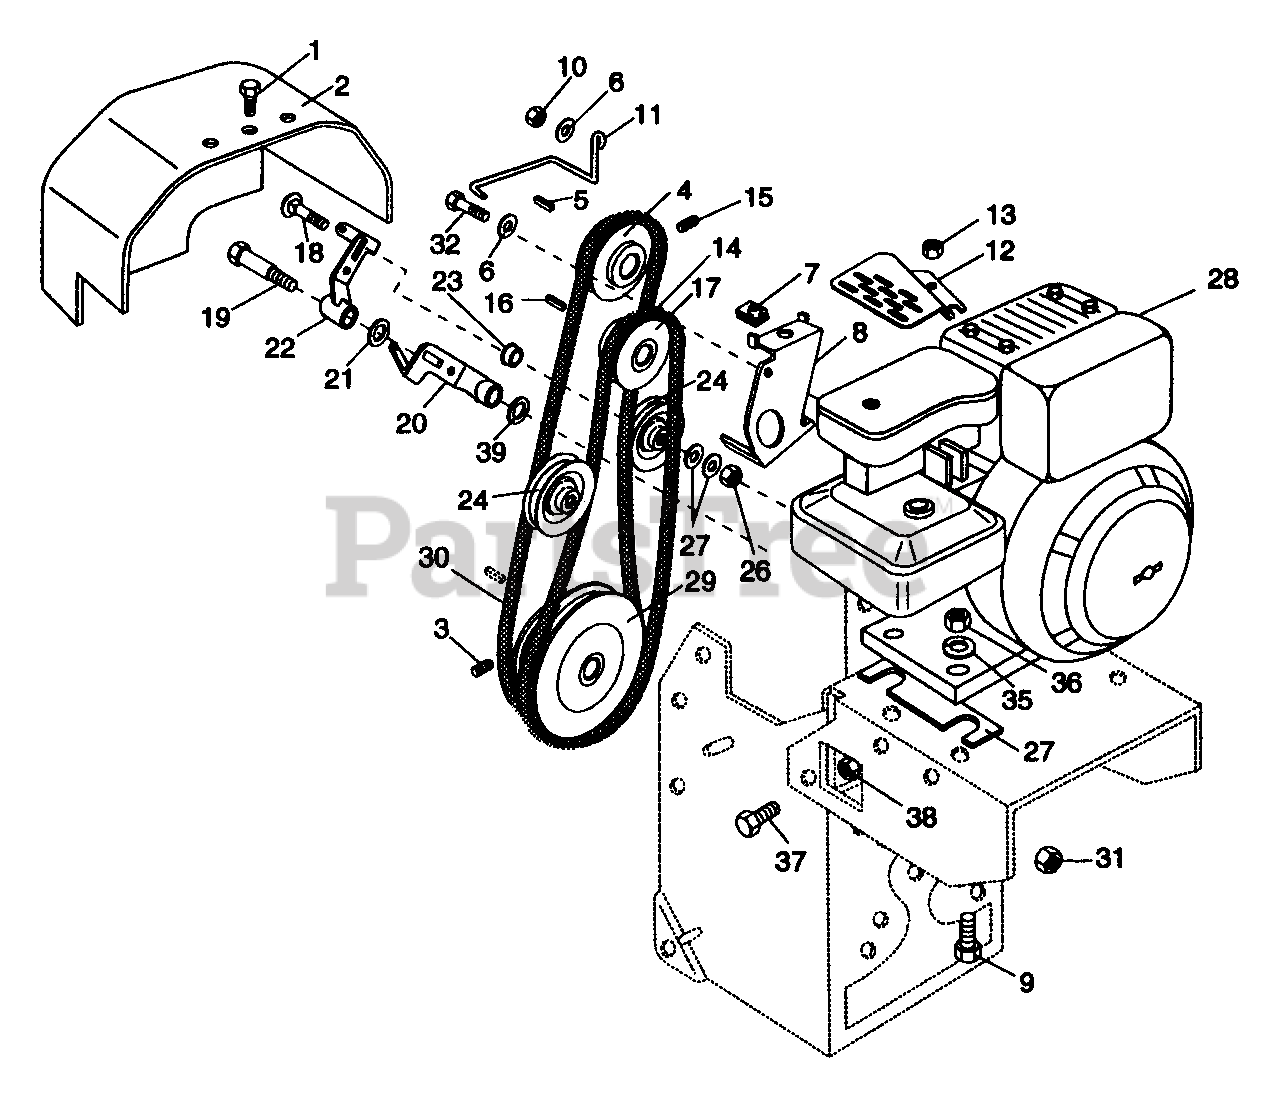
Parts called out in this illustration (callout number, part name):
1	BLT-HEX .25-20X.50 PL GR2
2	BELT COVER
3	SCR-SET .25-20X.38 SKHCUP OH
4	ENGINE SHEAVE
4	SHEAVE 4.000X.751
5	KEY-SQ .188X1.0X.188 SAE 8630
6	WSHR-FL-STL.281X.62X.065 PL
7	NUT-SPEED U-TYPE .250-20
8	REVERSE BELT FINGER
9	BLT-HEX .31-18X1.75 PL GR2
10	NUT-LK-CTR .250-20 PL
11	BELT FINGER
12	MUFFLER SHIELD
13	NUT-FLG. .312-18 PL
14	V-BELT, 3L-WRAPPED
15	SCR-SET .32-18X.38 SKHCUPNL OH
16	KEY-WDRF .125X.625X.250 SAE5
17	REVERSE SHEAVE
18	BLT-RDHDSQNK .31-18X1.25 SHTPL
19	WHEEL SHOULDER BOLT
20	IDLER ARM REV.
21	WSHR-FL-STL .520X.827X.062 YZ
22	IDLER ARM FWD
23	SPCR, BRG .315X.50X.688X.281
24	IDLER
25	WSHR-FL-STL .38X.875X.083 PL
26	NUT-LK .312-18 GR A PL
27	SHIM
27	Shim
28	5 HP BRIGGS ENG 135292-0180-01
29	PLY-DBLV 5.50 X.75 W/KEY SALEM
29	SHEAVE , DOUBLE W/.312 SC
30	V-BELT, 4L-WRAPPED
31	NUT-LK-CTR .375-16 GR A PL
34	SCR-SET .32-18X.38 SKHCUPNL OH
35	WSHR-LK .312X.097 PL HVY
36	NUT-HEX .312-18
37	BLT-HEX .38-16X.75 PL GR5
38	NUT-LK TOP .375-16 GR C YWZC
39	WSHR-FL-STL .531X1.062X.095 PL
